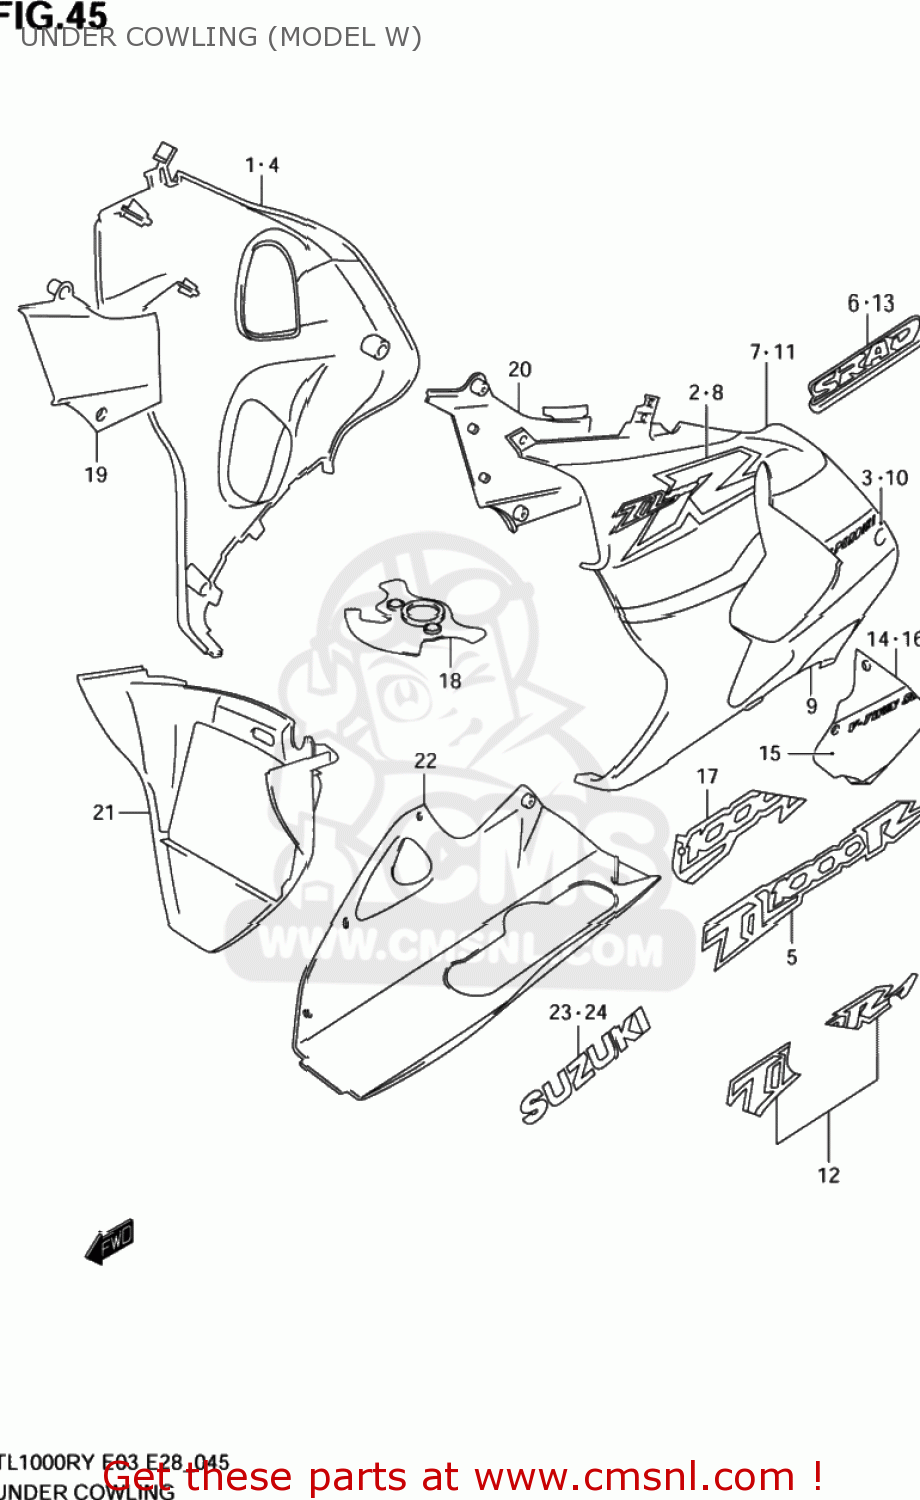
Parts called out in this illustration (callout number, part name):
1	COWLING ASSY,UNDER,R
2	EMBLEM,UNDER
3	TAPE,UNDER,RIGHT
4	COWLING ASSY,UNDER,R(YELLOW)
5	EMBLEM,UNDER,1000R,R
6	EMBLEM,COWLING UNDER
7	COWLING ASSY,UNDER,L
8	EMBLEM,COWLING UNDER,L
9	TAPE,UNDER LWR,L
10	TAPE,UNDER UNDER,L
11	COWLING ASSEMBLY,UNDER,LEFT (Y
12	TAPE(1000R),UNDER UNDER,L
13	EMBLEM,COWLING UNDER
14	LID,UNDER,L(WHITE)
15	EMBLEM,LID,L
16	LID,UNDER,L(YELLOW)
17	EMBLEM,LID,L
18	COVER,LWR BRACKET
19	COWLING,UNDER INNER,R
20	COWLING,UNDER INNER,L
21	COWLING,UNDER CTR
22	COWLING ASSY,UNDER RR
23	EMBLEM,UNDER COWL RR,R
24	EMBLEM,UNDER RR
